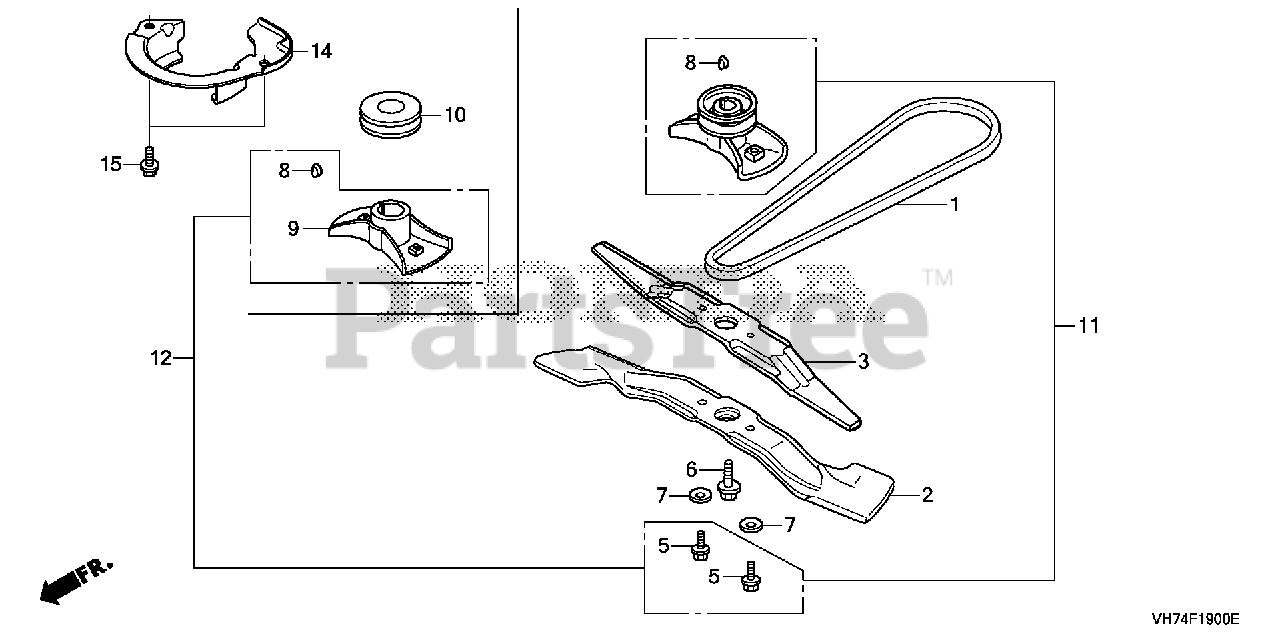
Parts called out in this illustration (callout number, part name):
1	V-BELT (3L-38.6)
2	BLADE, ROTARY
3	BLADE, ROTARY (UPPER)
5	BOLT, HEX. (10X25)
6	BOLT, FLANGE (3/8-24X1")
7	WASHER, SPRING (10MM)
8	KEY, WOODRUFF (3/16X5/8)
9	HOLDER, BLADE
10	PULLEY, DRIVE
12	HOLDER KIT, BLADE
14	GUIDE, ENGINE BELT
15	BOLT, FLANGE (6X14)
